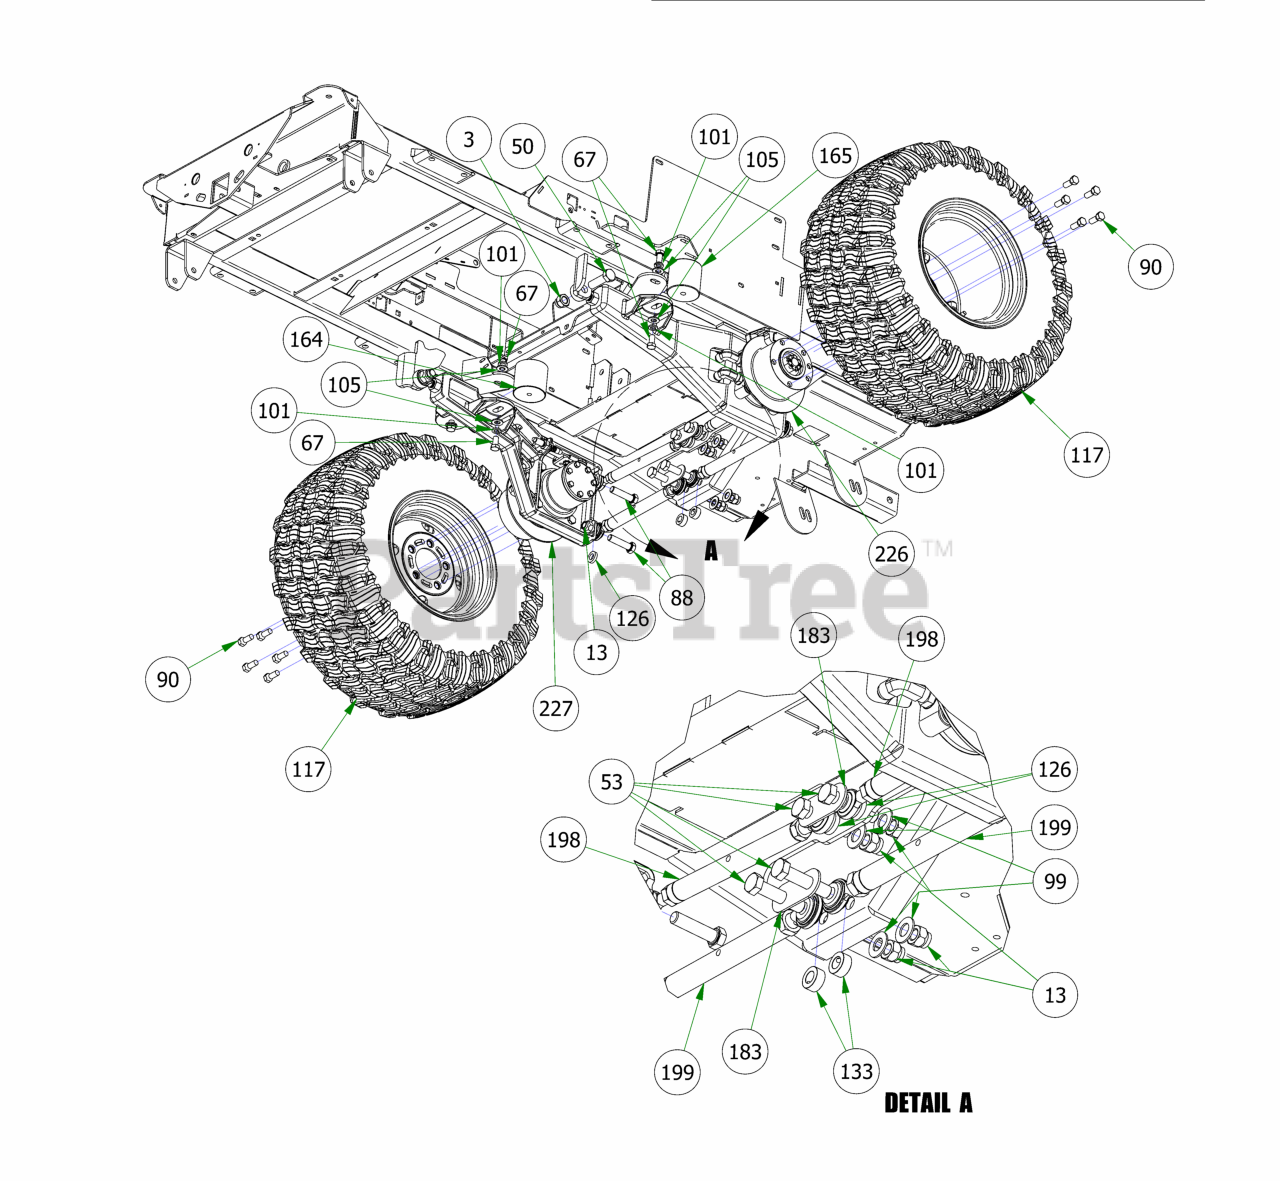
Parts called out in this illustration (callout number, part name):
3	3/4-10 NYLON INSERT LOCKNUT ZINC
13	5/8-11 NYLON INSERT LOCKNUT ZINC
23	2019 2" x .25 Rubber Grommet
50	3/4-10 X 2-1/2 HEX CAP SCREW (GR.5) ZINC
53	5/8-11 X 2-3/4 HEX CAP SCREW (GR.5) ZINC
67	1/2-13 X 1 HEX CAP SCREW (GR.5) ZINC
88	5/8-11 X 2-1/2 HEX CAP SCREW (GR.5) ZINC
90	1/2-20 x 60° Lug Bolts Zinc Grade 8
99	5/8" Flat Washer SAE Spec Grade 8
101	1/2 SPLIT LOCKWASHER (GR.8) ZINC/YELLOW
105	1/2 SAE FLAT WASHER (1-1/16" OD) GR.8 ZINC YELLOW
117	2019 Assy-26x12-12 Reaper Turf -10.5" Rim
126	Spacer 1.125OD x .625 ID x .250 Length
133	5/8 SOLID SHAFT COLLAR (W/1 SET SCREW) ZINC
164	Vibration Mount-Blue Dot
165	Vibration Mount-Green Dot
183	Suspension Gusset Outlaw
198	Suspension Radius Rod Assembly
199	Suspension Radius Rod Assembly
226	Renegade Trailing LH Arm Assy
227	Renegade Trailing RH Arm Assy
230	Renegade Gas Frame - Powdercoated
